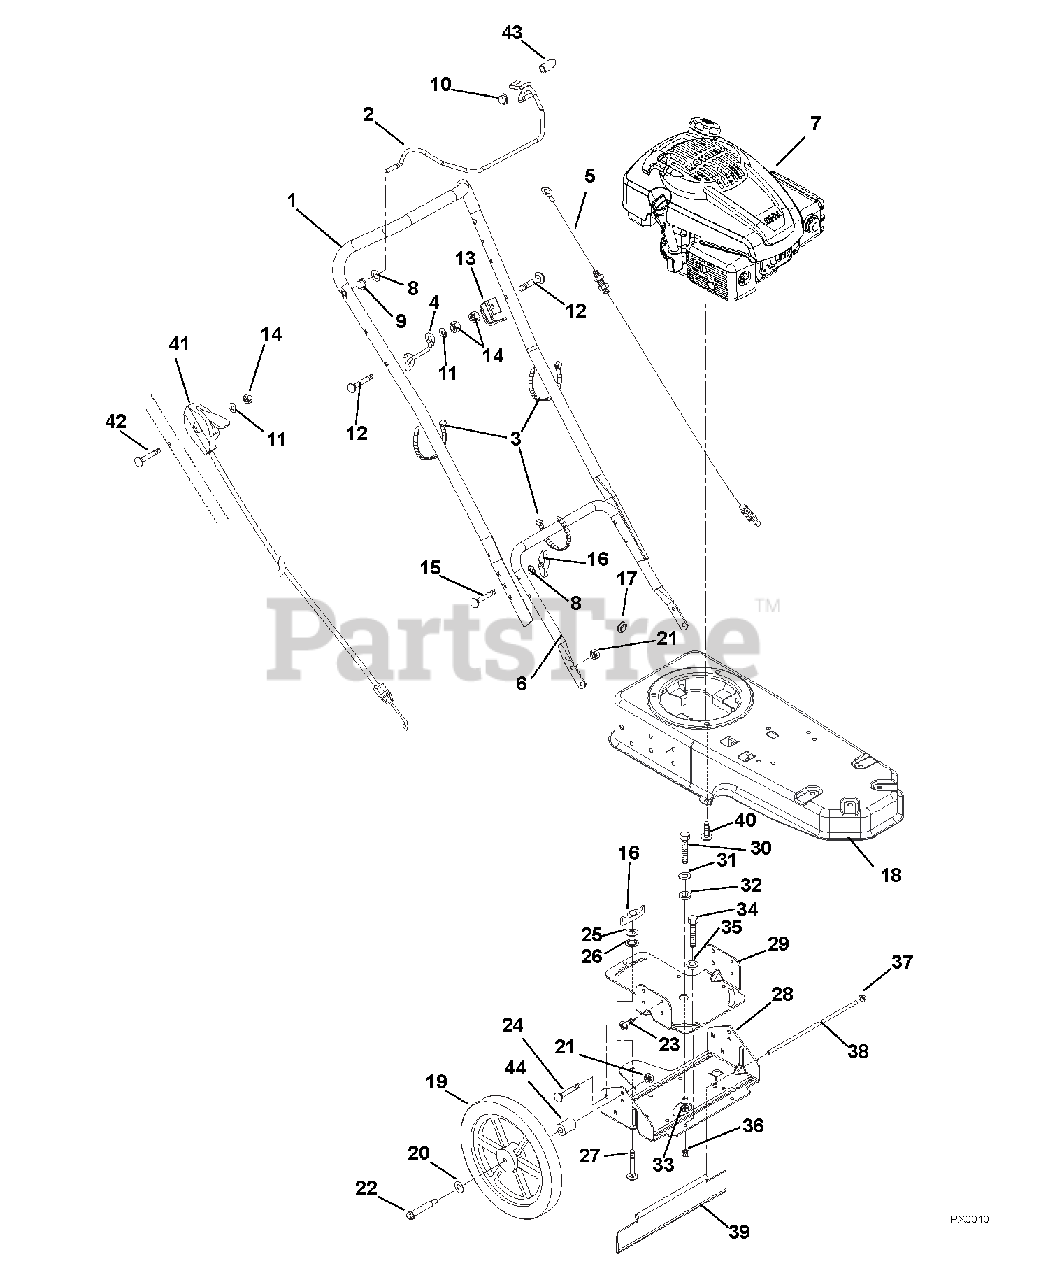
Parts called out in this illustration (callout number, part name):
1	HANDLEBAR - UPPER
2	BAIL SS LF
3	CABLE TIE LG 5-1/2
4	GUIDE - PULLCORD
5	CABLE - CONTROL
6	HANDLEBAR - LOWER
7	KOHLER XT8
8	@WSHR-FL-STL.344X.688X.065YWZC
9	BSHG-FLG .325X.444X.440X.560
10	PUSH NUT, .25
11	@WSHR-FL-STL.281X.62X.065 YWZC
12	BLT-RDHDXLSQNK.25-20X1.25 G5ZC
13	ANCHOR - CABLE
14	@NUT-LK-CTR .25-20 YWZC
15	BLT-RDHDSQNKFT .31-18X2.0 G5YZ
16	KNOB - WING .312-18 UNC
17	GROMMET .50 ID
18	FRAME - TRIMMER
19	WHEEL, 14" STRING TRIMMER
20	WSHR-FL-STL .52X.827X.062 YWZC
21	@NUT-LK-CTR .38-16 YWZC
22	BLT-SHLDR .38-16X2.50 HWH G5
23	@SCR-TAP .38-16X.75 HWH TR YWZ
24	@BLT-RDHDSQNK .38-16X.75 G5YZ
25	@WSHR-FL-STL.38X.875X.083 YWZC
26	NUT-PUSH .312
27	@BLT-RDHDSQNK .31-18X1.00 G5YZ
28	BRACKET - AXLE - SWIVEL
29	BASE - SWIVEL
30	@BLT-HEX .50-13X1.00 GR5 YWZC
31	@WSHR-FL-STL.563X1.38X.109YWZC
32	SPACER .531 X 1.00 X .225
33	@NUT-LK-CTR .50-13 YWZC
34	@BLT-HEX .31-18X1.00 GR5 YWZC
35	BSHG-FLG .32X.500X.344X.880
36	@NUT-LK-CTR .31-18 YWZC
37	NUT-PUSH .312 DIA. PAL
39	GUARD - REAR - SWIVEL
40	@SCR-TAP .38-16X1.00 HWH TR YZ
41	CABLE, BRIGGS TRIMMER THROTTLE
42	BLT-RDHDXLSQNK .25-20X2.0 G5YZ
43	CAP, VINYL, .25 ID
44	BSHG-SLV .377X.624X.235
